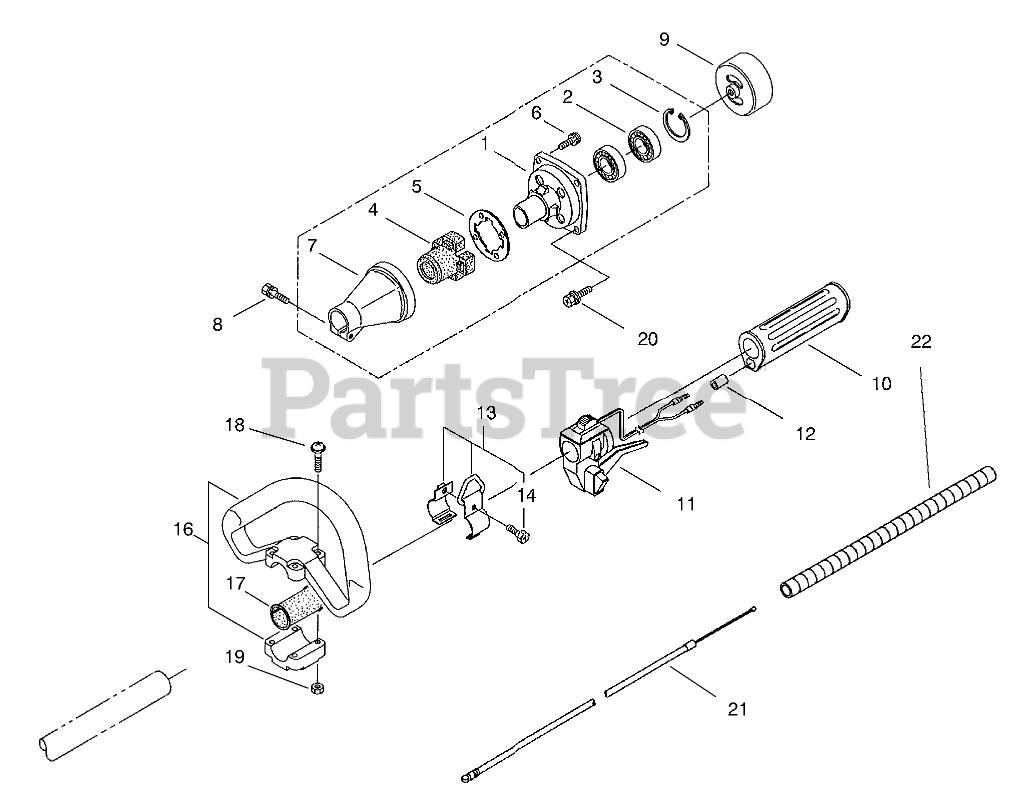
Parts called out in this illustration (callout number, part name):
1	CASE - BEARING
2	BEARING
3	RING - SNAP
4	BUFFER
5	WASHER
6	SCREW
7	ADAPTER-DRIVESHAFT TUBE
9	DRUM - CLUTCH
10	GRIP - SHAFT
11	TRIGGER - THROTTLE
12	GUIDE - OUTER
13	Hanging Bracket Assembly (Incl. Ref. #14)
16	HANDLE - LOOP
17	PACKING
18	SCREW
19	NUT M5
21	CABLE - THROTTLE
22	TUBE - PLASTIC
